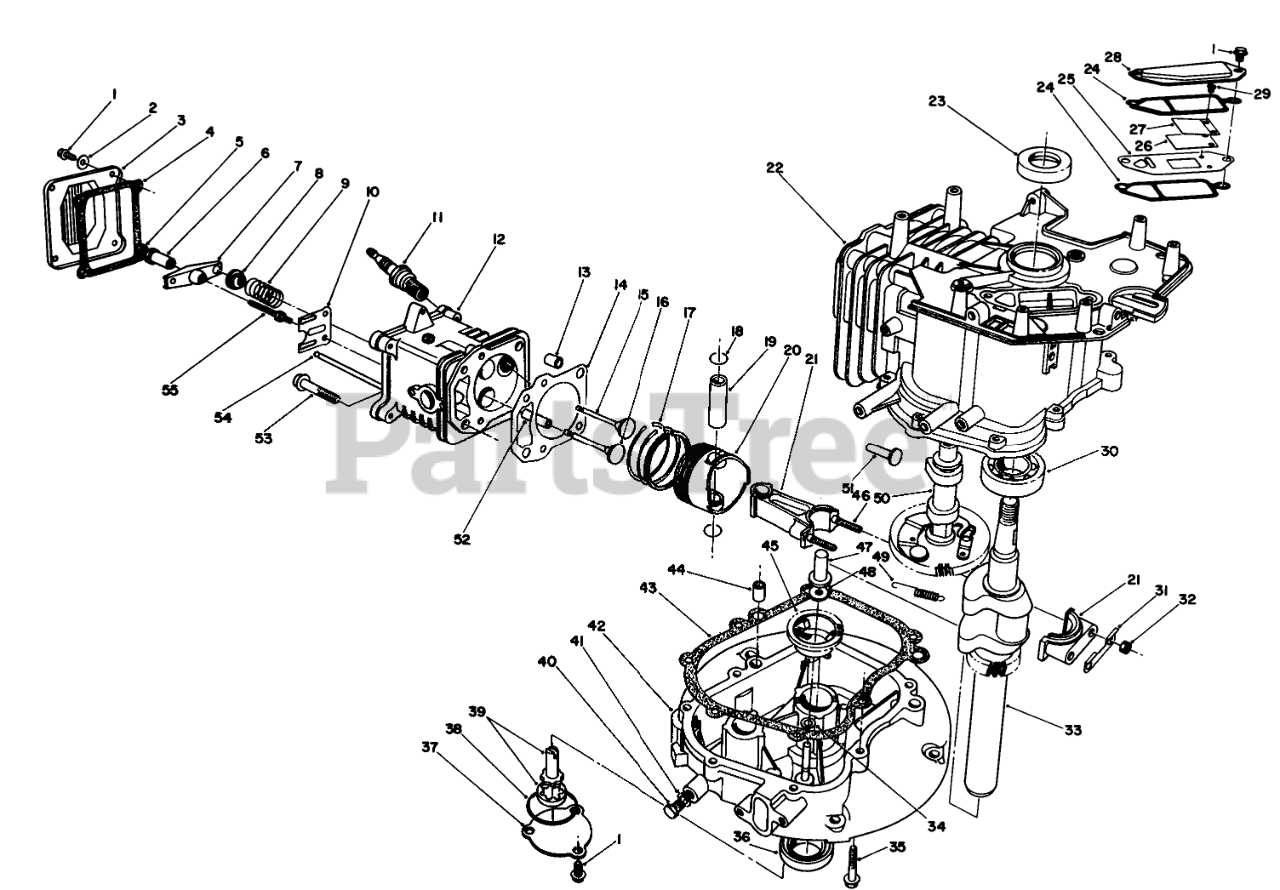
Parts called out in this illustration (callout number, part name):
2	WASHER
3	COVER
4	GASKET
6	PIVOT
8	RETAINER
9	SPRING
10	GUIDE
11	SPARK PLUG
12	Head-Cylinder (Incl. Ref. #52)
14	GASKET
15	VALVE-INTAKE
16	VALVE-EXHAUST
17	RING SET
18	CIRCLIP
20	PISTON
21	Connecting Rod Assembly (Incl. Ref. #31, 32 & 46)
22	Block-Engine (Incl. Ref. #23 & 30)
24	GASKET
25	Plate-Breather
26	COVER
27	Screw-Reed Valve
28	Retainer-Reed Valve
29	Valve-Reed
30	BEARING
31	Plate-Lock
33	CRANKSHAFT
34	WASHER
37	COVER
38	O-RING
39	OIL PUMP
40	OIL DRAIN PLUG
41	GASKET
42	Crankcase
43	GASKET
45	GOVERNOR FLYWEIGHT ASM
47	PLUNGER
48	WASHER
49	SPRING
50	Camshaft Assembly (Incl. Ref. #49)
51	TAPPET
52	GUIDE
